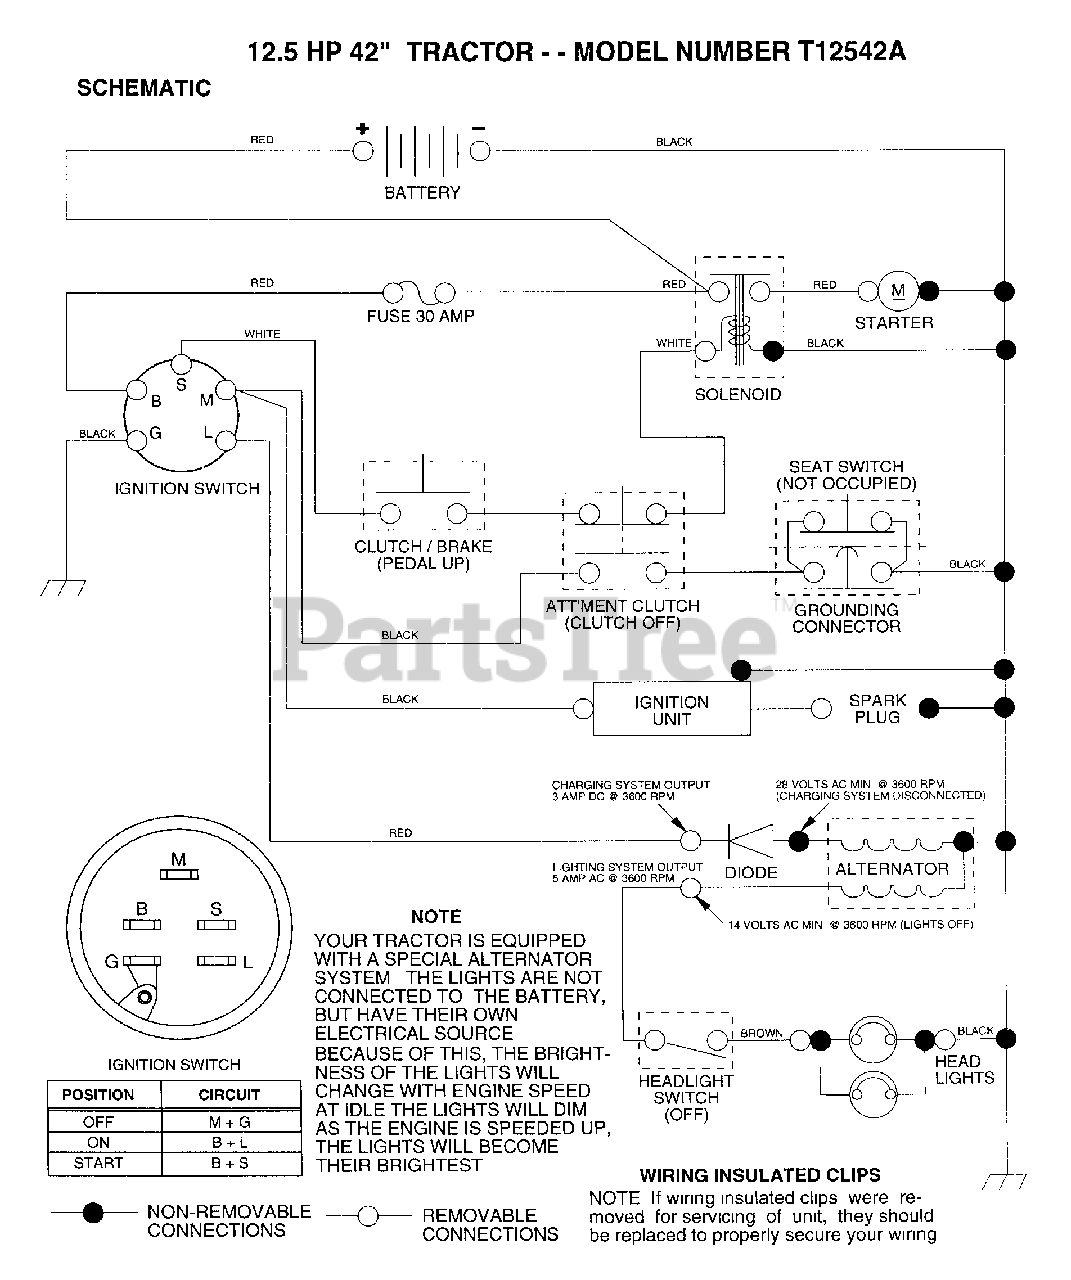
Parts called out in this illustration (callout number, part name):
4	"SPRING, DETENT LT"
5	"SCREW, SET LT"
6	KIT SHIFTER ASM
7	SHIFTER BOOT
8	SCREW TAP W/SEAL
9	SQUARE RING
10	RETAINING RING LT
11	ASM KIT SHIM 4689
12	"FLANGE, BEARING"
13	WASHER T
14	WOODRUFF KEY
15	AS KIT INPUT SHFT
16	PINION 14T T
17	"RING,RETAINING LT"
18	"CHAIN,24 PTCH LT"
19	BEARING.FLNG.5510
20	GEAR SPUR 14T
21	COLLAR CLUTCH
22	ASM KIT CLTCH KEY
23	NUT.LOCK.5/16-24
24	SHAFT INTERM
25	WOODRUFF KEY
26	"RING,RETAINING LT"
27	SPROCKET 18T T
28	SPACER YT
29	KIT.GEAR.12/37TH
32	GEAR 25T LT
33	GEAR SPUR 22 TT
34	SPUR GEAR 19T
35	"WASHER, PLAIN LT"
36	WASHER 025
37	SPACER
38	ASSM GEAR COMB
39	SHAFT IDLER
40	SPACER T
41	SPROCKET 9T LT
43	ASM KIT SHIM
44	SHAFT T
48	"GEAR, SPUR 25T LT"
49	GEAR 28T T
50	"GEAR, SPUR 31T LT"
51	WASHER 060
52	NEOPRENE WASHER
53	WASHER 031
55	GEAR 15T T
56	"RING,RETAINING LT"
58	SHAFT T
59	GEAR 1ST T
62	PUCK T
63	BRAKE DISC. T
64	SPACER LT
66	PIN T
69	WASHER LT
71	"SCREW, TAPPING LT"
72	PUCK T
